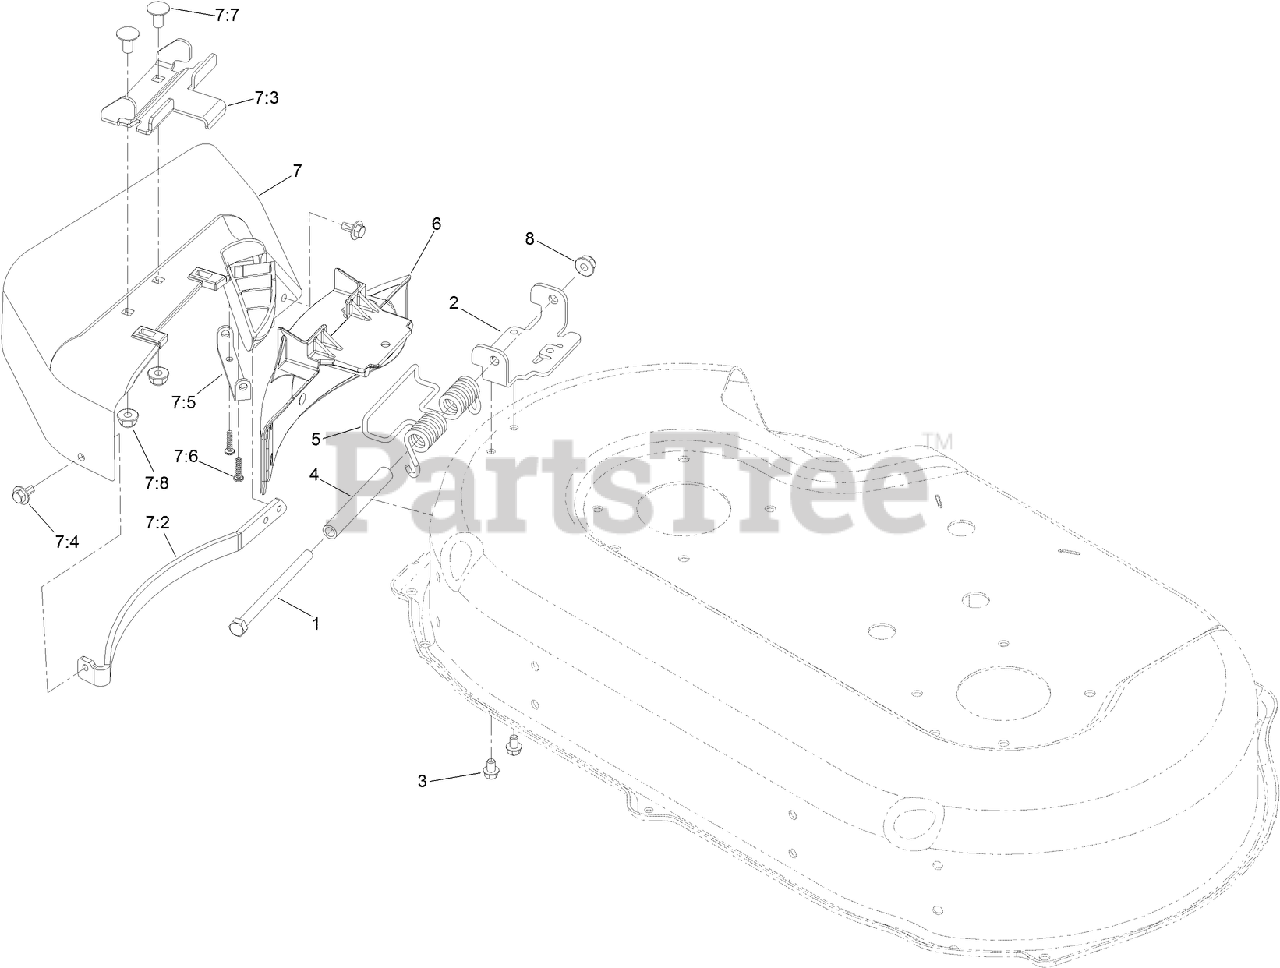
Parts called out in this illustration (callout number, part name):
1	SCREW-HH
3	SCREW-HWH
4	SPACER
5	SPRING-TORSION
6	COVER-DISCHARGE
7	SIDE DISCHARGE CHUTE ASM
7:2	GUARD-CHUTE
7:3	BRACKET-CHUTE
7:4	SCREW-HHFTF
7:5	BRACKET-COVER
7:6	SCREW-PPH
7:7	SCREW-CARR
7:8	NUT-HF, NI
8	NUT-HF, NI
